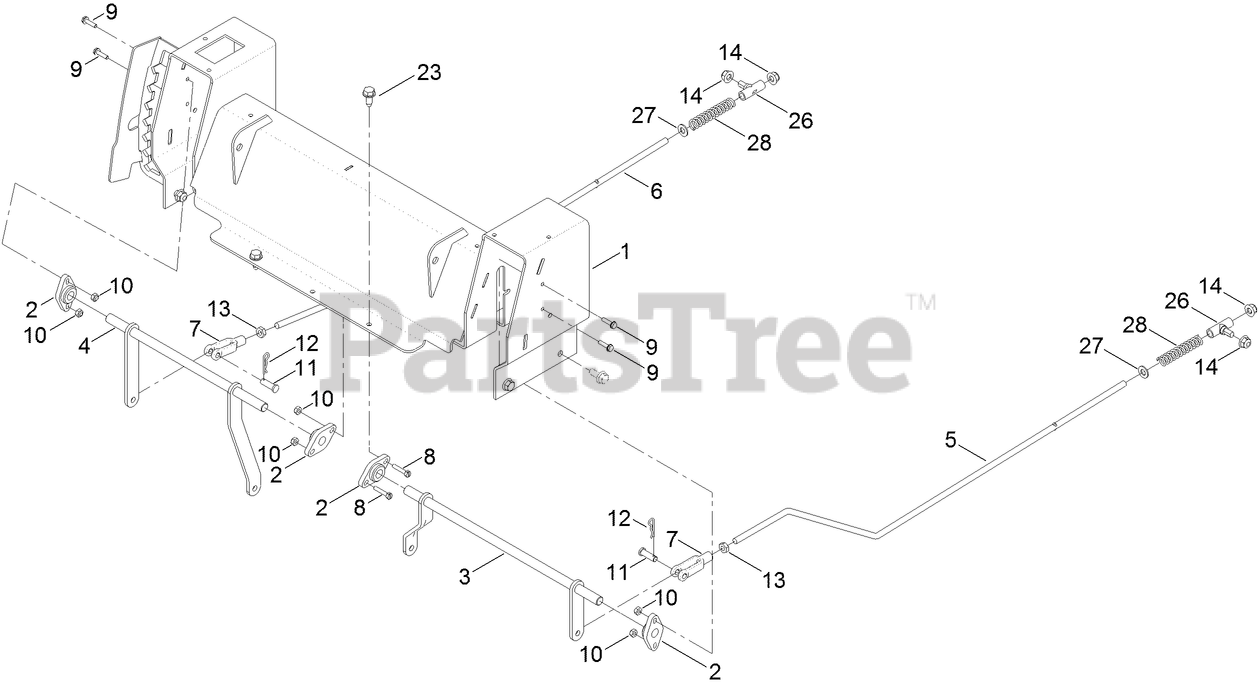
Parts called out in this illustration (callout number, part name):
1	CONTROL BOX ASM
2	BEARING-FLANGE
3	BELLCRANK-LH
4	BELLCRANK-RH
5	ROD-HYDRO, LH
6	ROD-HYDRO, RH
7	YOKE-ADJUSTABLE
9	SCREW-HWH
10	NUT-LOCK, NI
11	PIN-CLEVIS
12	PIN-COTTER
13	NUT-JAM
13	SCREW-HHF
14	NUT-HF, NI
23	SCREW-HWHTF
26	MOUNT-ROD, HYDRO
27	WASHER-PLAIN
28	SPRING-RETURN, NEUTRAL
